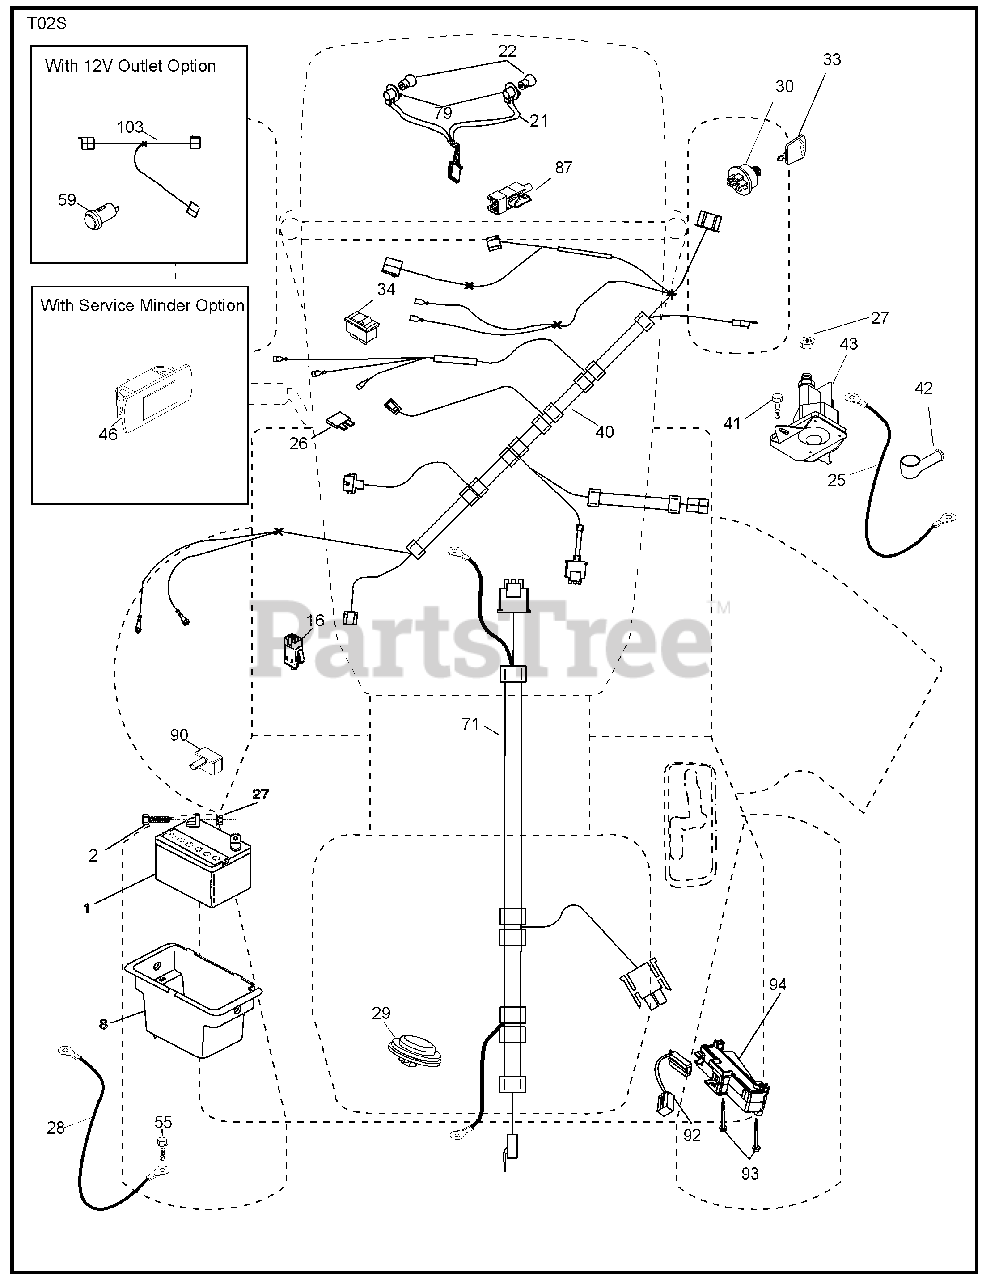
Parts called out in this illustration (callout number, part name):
1	Battery
2	Bolt Hex Head 1/4-20 x 3/4
8	Box Battery
16	Switch Interlock Push-In
21	Harness Socket Light w/4152J
22	Bulb Light
25	Cable Starter
27	Nut Keps Hex 1/4-20 unc
28	Cable,Ground
29	Switch, Seat
30	Switch, Ign
33	Key, Ignition
34	Switch Light/Reset
40	Harness Ign. Dash
41	Screw Thd Cut 1/4-20 x 1/2
42	Cover, Terminal
43	Solenoid
55	Screw Thdrol 5/16-18 x 3/4
71	Harness Chassis
79	Socket Asm Bulb Twistlock
87	Switch Interlock Clutch Cable
90	Cover, Terminal Battery
92	Harness Pigtail Reverse Switch
93	Screw Plastite 10-14 x 2.0
94	Module Reverse ROS
